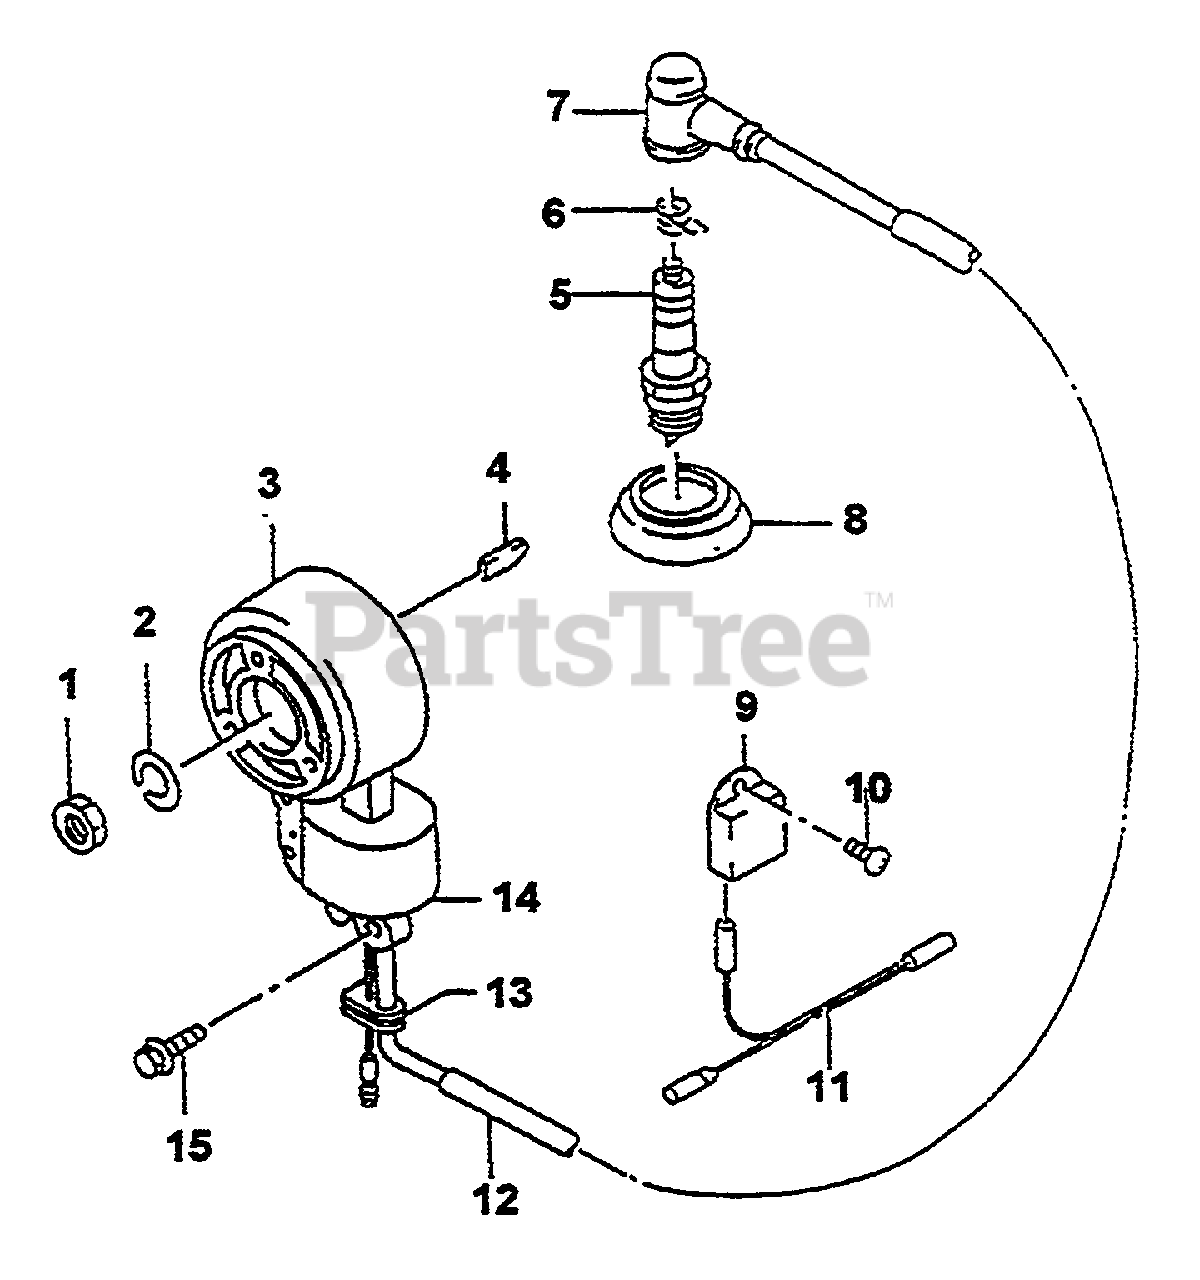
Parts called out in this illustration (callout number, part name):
5	SPARK PLUG
6	TERMINAL
7	CAP
11	LEAD WIRE
14	COIL ASSY
